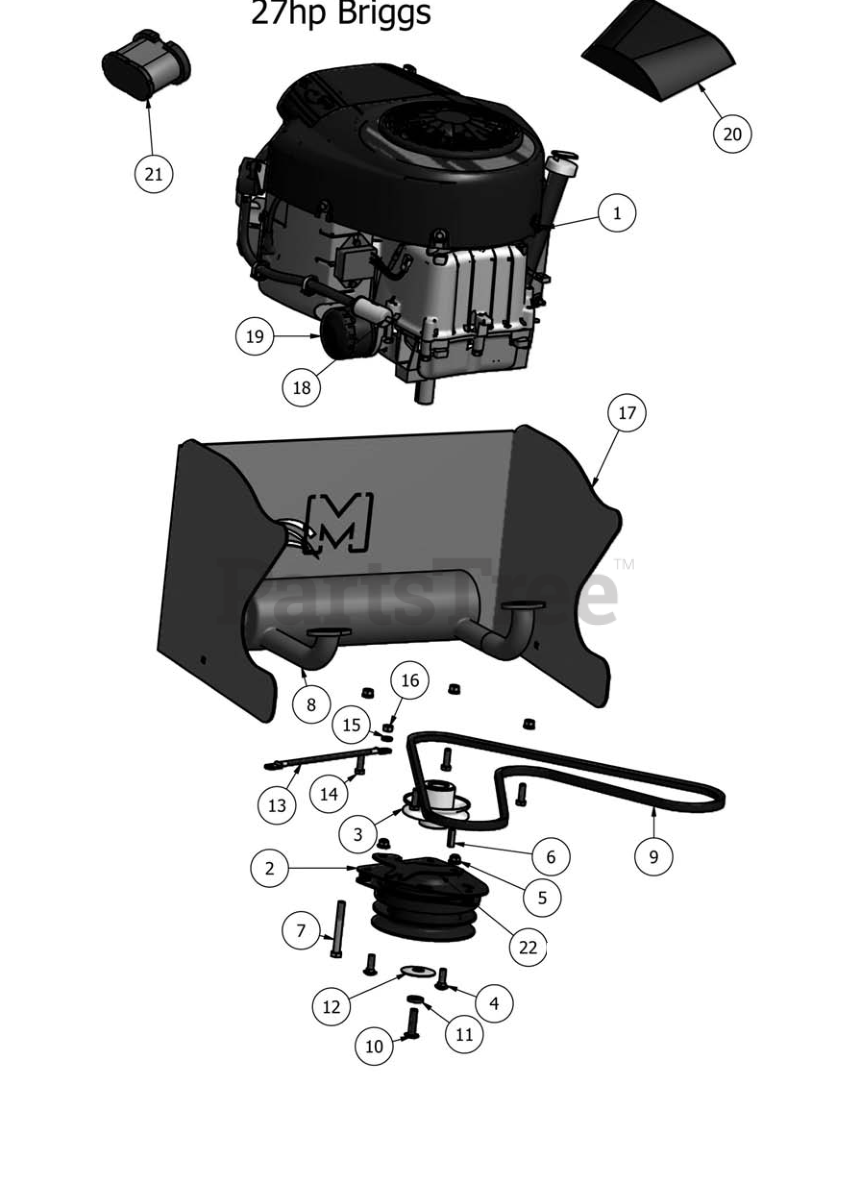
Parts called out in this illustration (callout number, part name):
1	27hp Briggs Pro Series
3	3-3/4" Motor Pulley
4	5/16" x 1" Carriage Bolt
5	5/16" Flange Nut
6	1/4" x 1" Key
7	3/8-16 x 3 1/2 Hex Bolt (Clutch Stop)
8	27HP Exhaust
10	MZ Crank Shaft Bolt
11	7/16" Lock Washer
12	Cup Washer
13	Ground Cable
14	3/8 x 1-1/8 Hex Bolt
15	5/16" Lock Washer
17	Engine Rear Plate
18	Fuel Filter
19	Oil Filter
20	Air Filter Cover
21	Air Filter& Pre-Cleaner 27hp Briggs
22	clutch Holder
